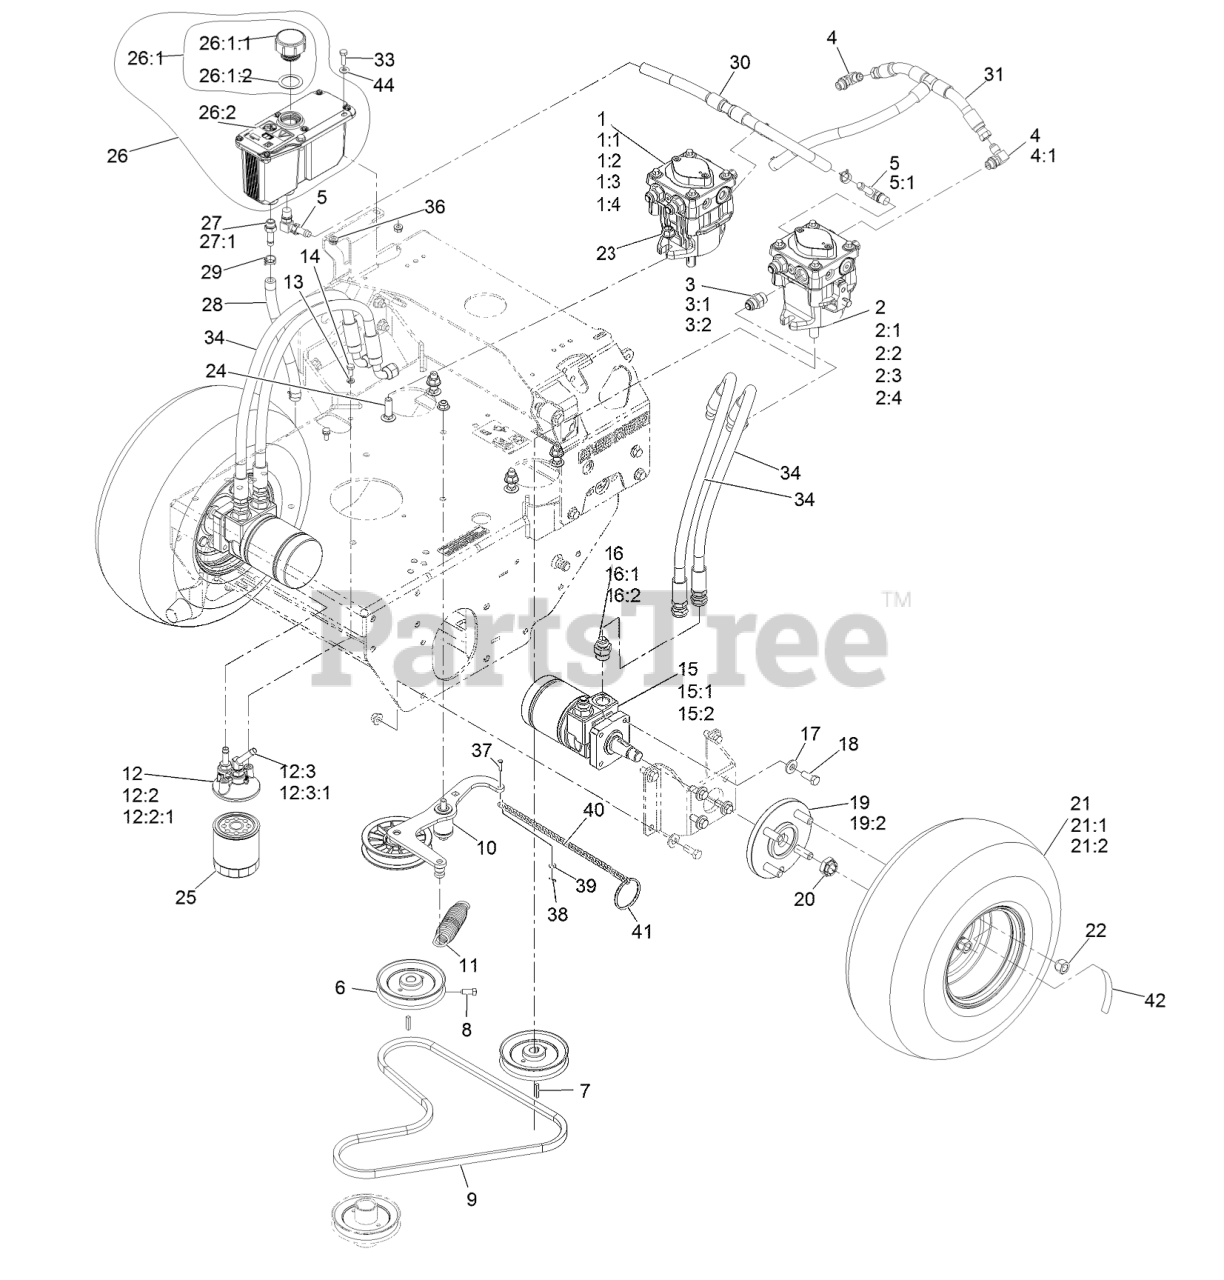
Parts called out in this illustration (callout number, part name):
1	RH HYD PUMP ASM
1:1	INPUT SHAFT KIT
1:2	BEARING-THRUST
1:3	CYLINDER BLOCK KIT
1:4	SEAL OVERHAUL KIT
2	LH HYD PUMP ASM
2:1	INPUT SHAFT KIT
2:2	BEARING-THRUST
2:3	CYLINDER BLOCK KIT
2:4	SEAL OVERHAUL KIT
3	FITTING-STRAIGHT
4	FITTING-ELBOW, 90 DEG
4:1	O-RING
5	FITTING-ELBOW, 90
5:1	O-RING
6	SHEAVE ASM
8	SCREW-SET, SQH
9	BELT
10	ASM, PUMP IDLER
11	SPRING-EXTENSION
12	ASM, FILTER HEAD
12:2	ADAPTER-STRAIGHT
12:2:1	O-RING
12:3	FITTING-BARBED, 45 DEG
12:3:1	O-RING
13	WASHER-LOCK
14	SCREW-HH
15	HYD MOTOR ASM
15:1	SEAL KIT
15:2	BEARING AND SEAL KIT
16	FITTING-STRAIGHT
16:1	O-RING
17	WASHER-BELLEVILLE
18	SCREW-HH
19	WHEEL HUB ASM
19:2	STUD-WHEEL
20	NUT-LOCK
21	WHEEL AND TIRE ASM
21:1	TIRE-TURFMASTER
21:2	RIM-WHEEL
22	NUT-LUG
23	NUT-HF, NI
24	BOLT-CARR
25	FILTER-25 MICRON, BI-DIRE
26:1	Reservoir-HYD
26:1:1	Cap-Reservoir, HYD
26:1:2	GASKET-CAP
26:2	DECAL-WARNING
27	ADAPTER-STRAIGHT
27:1	O-RING
28	HOSE-CHARGE
29	CLAMP-HOSE
30	HOSE-CASE DRAIN
31	HOSE-CHARGE
33	SCREW-HH
34	HYD HOSE ASM
36	NUT-HHF
37	PIN-CLEVIS
38	PIN-HAIR
39	WASHER-PLAIN
40	CHAIN-LINK, TWIST
41	RING-SPLIT
42	DECAL-TORQUE WHEEL LUG-HU
44	WASHER-FLAT
